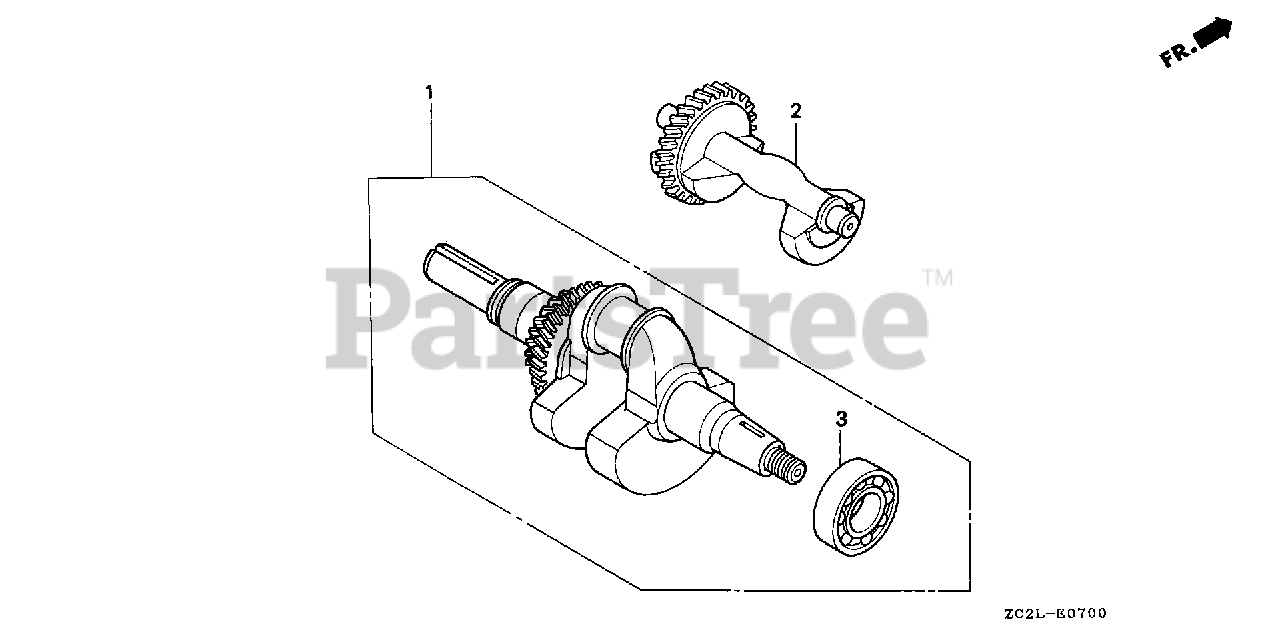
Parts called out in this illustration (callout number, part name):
1	CRANKSHAFT
2	WEIGHT, BALANCER
3	BEARING, RADIAL BALL (6207)
